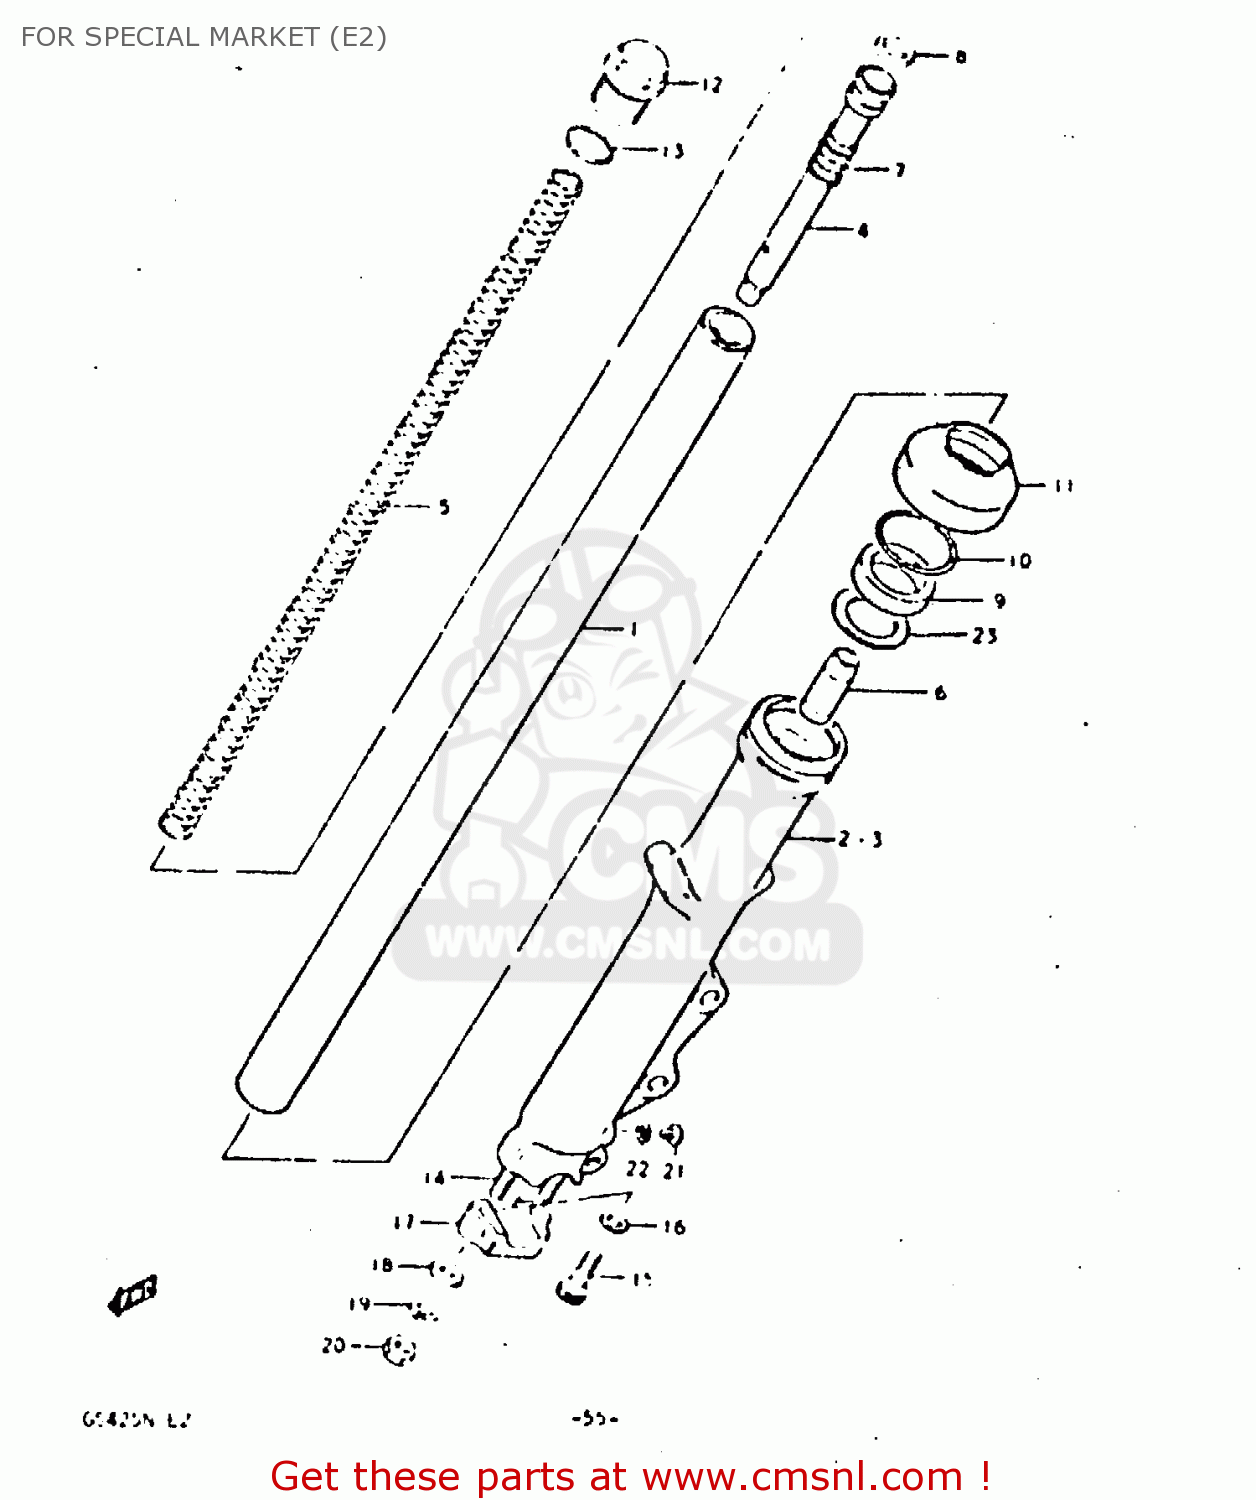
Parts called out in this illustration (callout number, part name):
1	TUBE,INNER
2	TUBE,FORK,LEFT,OUTER
3	TUBE,FORK,OUTER,RIGHT
4	CYLINDER,FRONT FORK
5	SPRING
6	PIECE,OIL LOCK
7	SPRING,REBOUND
8	RING,PISTON
9	OIL SEAL,FRONT FORK
10	CIRCLIP,FORK OIL SEAL
11	BOOT
12	BOLT
13	O RING
14	STUD 8X25
15	BOLT
16	GASKET (NAS)
17	HOLDER,AXLE
18	WASHER
19	LOCK WASHER
20	NUT
21	SCREW
22	GASKET (NAS)
23	SPACER,OIL SEAL
